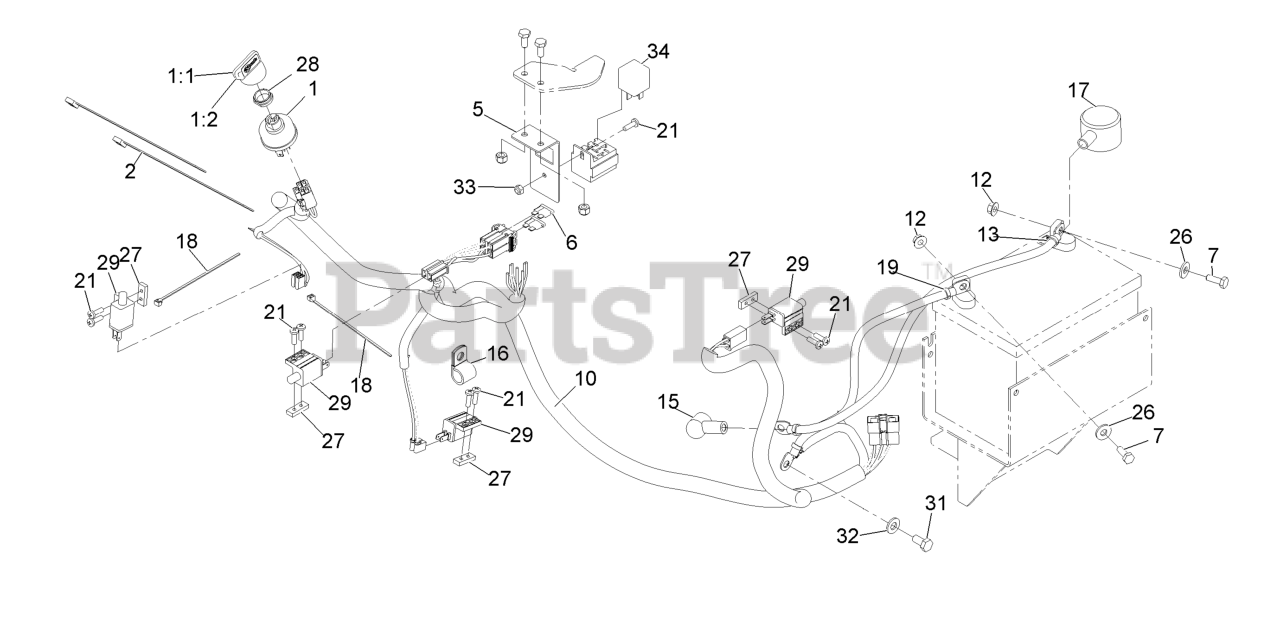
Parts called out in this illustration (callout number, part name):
1:1	KEYS-IGNITION (SPARE PAIR
1:2	KEY-IGNITION
2	TIE-PLASTIC
5	BRACKET-FUSE AND RELAY
6	FUSE-BLADE TYPE, 20 AMP
7	SCREW-HH
13	ASM,POSITIVE BATTERY CABL
15	INSULATOR-SOLENOID
16	CLIP-LOOM
17	INSULATOR-BATTERY
18	TIE-CABLE
19	CABLE-BATTERY, NEGATIVE
21	SCREW-PPH
26	WASHER-FLAT
27	PLATE-TAPPED
28	NUT-SWITCH, IGNITION
29	SWITCH-OPEN, NORMALLY
31	SCREW-HH
32	WASHER-PLAIN
33	NUT-LOCK, NI
